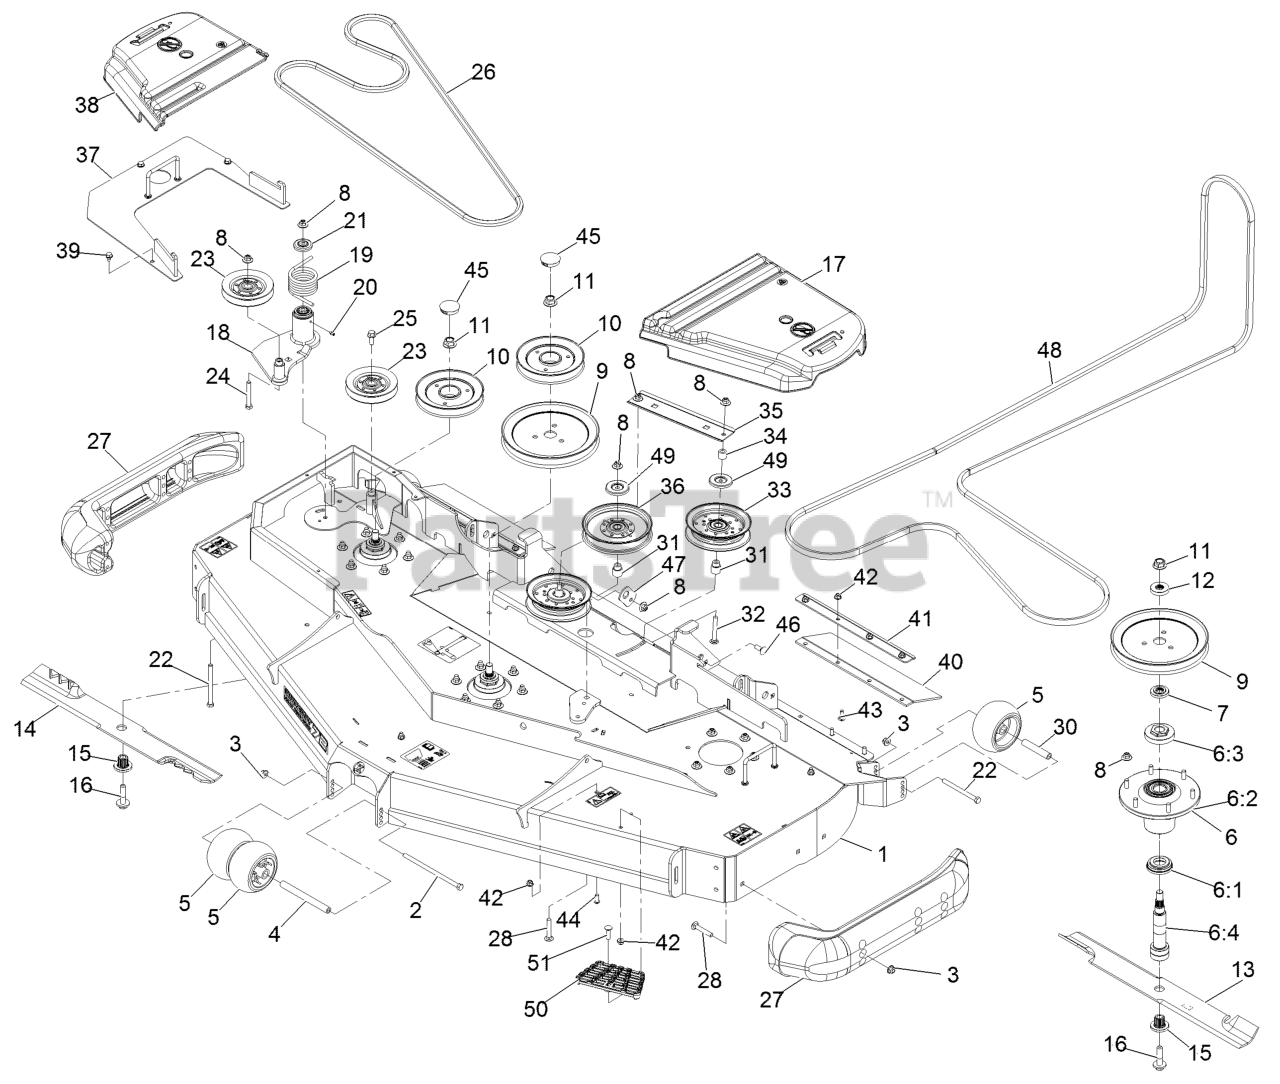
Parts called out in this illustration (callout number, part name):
1	DECK-RD72, W/DECALS
2	SCREW-HH
3	NUT-HF, NI
4	SPACER-WHEEL
5	ROLLER-SCALP, ANTI
6	ASM,SPINDLE HOUSING
6:1	GUARD,BOTTOM
6:2	ASM,CUTTER HOUSING
6:3	NUT, SPINDLE 7/8-14
6:4	SPINDLE,DOUBLE SPLINE
7	SPACER,SPLINED STEPPED
8	Nut-Nyloc 3/8-16 Flg
9	SHEAVE,BLADE DRIVE 9.00
10	SHEAVE-RD, REVERSE DRIVE
11	NUT-FLANGE, CENTERLOCK
12	SPACER,SPLINED
15	BUSHING,SPLINED
16	SCREW,SEMS 1/2-20 X 2.19
17	COVER-BELT, LH
18	IDLER ASM
19	SPRING-TORSION
20	FITTING-GREASE
21	GUARD-TOP
22	SCREW-HH
24	SCREW-HH
25	SCREW-HHF
27	SKID-BUMPER, DECK
28	Bolt-Carriage 3/8-16 X 2 1/4
30	TUBE-SPANNER
31	BUSHING-IDLER
32	SCREW-CARR
33	IDLER-PULLEY, FLAT
35	GUIDE-RD BELT
36	IDLER-PULLEY, FLAT 6.00X1
37	COVER-RD72 REVERSE DRIVE
38	COVER-BELT, RH
40	GUARD-TIRE RD72
41	SUPPORT-OUTER FLAP
42	NUT-HF, NI
43	SCREW-CARR
44	SCREW-HSBH
45	PLUG,BLACK NYLON 1.75
46	BOLT-CARR
47	PLATE,DECK STRUT
48	BELT-V
49	SHIELD-DUST
50	STEP-DECK
51	Bolt-Carriage 5/16-18 X 1 1/4
